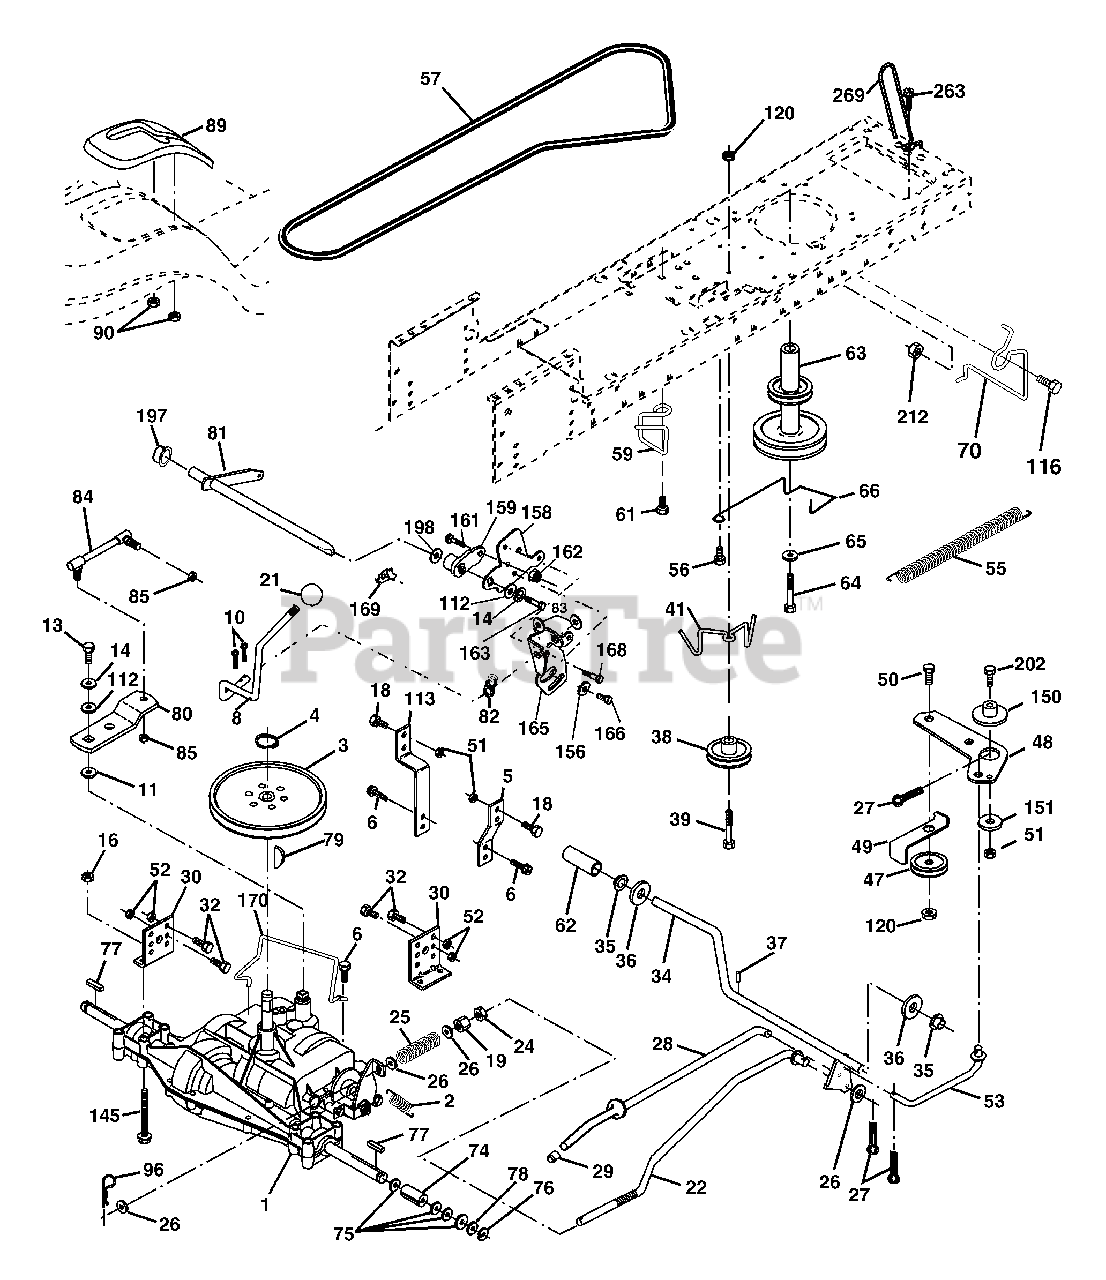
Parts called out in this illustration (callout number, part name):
8	Rod Shift
10	Pin Cotter 1/8 x 1 CAD
14	Washer Lock Hvy Helical
15	Bolt, Hex FLGHD 5/16-18 Gr. 5
16	Nut Lock Hex W/Ins 5/16-18 unc
19	Nut Lock Hex W/Wsh 3/8-16 unc
21	Knob, Round 1/2-13
22	Rod, Brake Hydro
24	Nut
25	Spring, Brake Rod
26	Washer
27	Pin Cotter 1/8 x 3/4 CAD.
28	Rod, Parking Brake
29	Cap, Parking Brake
30	Bracket, Transaxle
32	Bolt Hex Hd 5/16-18 unc x 3/4
34	Shaft, Foot Pedal
35	Bearing, Nylon
36	Washer
37	Pin, Roll
38	Pulley, Composite
39	Bolt Rdhd 3/8-16 unc x 2-3/4 Gr. 5
41	Keeper, Belt Idler
47	Pulley, Idler, V-Groove
48	Bellcrank Clutch Grnd Drv STL
49	Retainer, Belt
50	Bolt Carr Sh 3/8-16 x 1-1/2 Gr. 5
51	Nut Crownlock 3/8-16 unc
52	Nut Crownlock 5/16-18 unc
53	Link, Clutch
55	Spring, Return, Clutch
56	Screw 3/8-16 x 1-1/4
57	V-Belt, Ground Drive
59	Keeper, Center Span
61	Screw 3/8-16 x .875
62	Cover, Pedal
63	Pulley, Engine
64	Bolt Hex 7/16-20 x 4 x Gr. 5-1.5 Thr
65	Washer
66	Keeper Belt Engine
70	Guide Belt
71	Strap Torque Lh Hydro
73	Strap Torque Rh Hydro
74	Spacer, Axle
75	Washer 25/32 x 1-1/4 x 16 Ga.
76	E-Ring
77	Key, Square
78	Washer 25/32 x 1-5/8 x 16 Ga.
81	Shaft Asm. Cross Hydro
82	Spring Torsion T/A
83	Washer 17/32 x 3/4 x 16 Ga.
84	Link Transaxle
89	Console, Shift
90	Nut Self-Thd Wsh-HD 1/4 Zinc
95	Control Asm Bypass Hydro
96	Retainer Spring 1" Zinc/Cad
116	Bolt RDHD SQNK 3/8-16 unc x 1
120	Nut Lock Flg 3/8-16 unc
150	Spacer Retainer
151	Washer 13/32 x 2 x 10 Ga.
156	Washer Srrted 5/16 ID x 1.125
158	Bracket Shift Mount
159	Hub Shift
161	Bolt Rdhd Sqnk 1/4-20 x 3/4 Gr. 5
162	Nut Crownlock 1/4-20 unc
163	Bolt Hex Fin 1/4-20 unc x 1 Gr. 5
164	Washer 9/32 x 3/4 x 10 Ga.
165	Bracket Pivot Lever
166	Screw 5/16-18 x 5/8
168	Bolt Shoulder 5/16-18 x .561
169	Plate Fastening Lt
197	Nyliner Snap-In 5/8" ID
198	Washer Nyl 7/8 ID x .105
199	Bolt Shoulder 5/16-18 unc
200	Bolt Rdhd Sqnk 5/16-18 unc x 1
202	Bolt Carr Sh 3/8-16 x 1-3/4 Gr. 5
212	Nut Hex flange Lock
271	Screw Hexwsh Thdr 3/8-16 x 3/4
